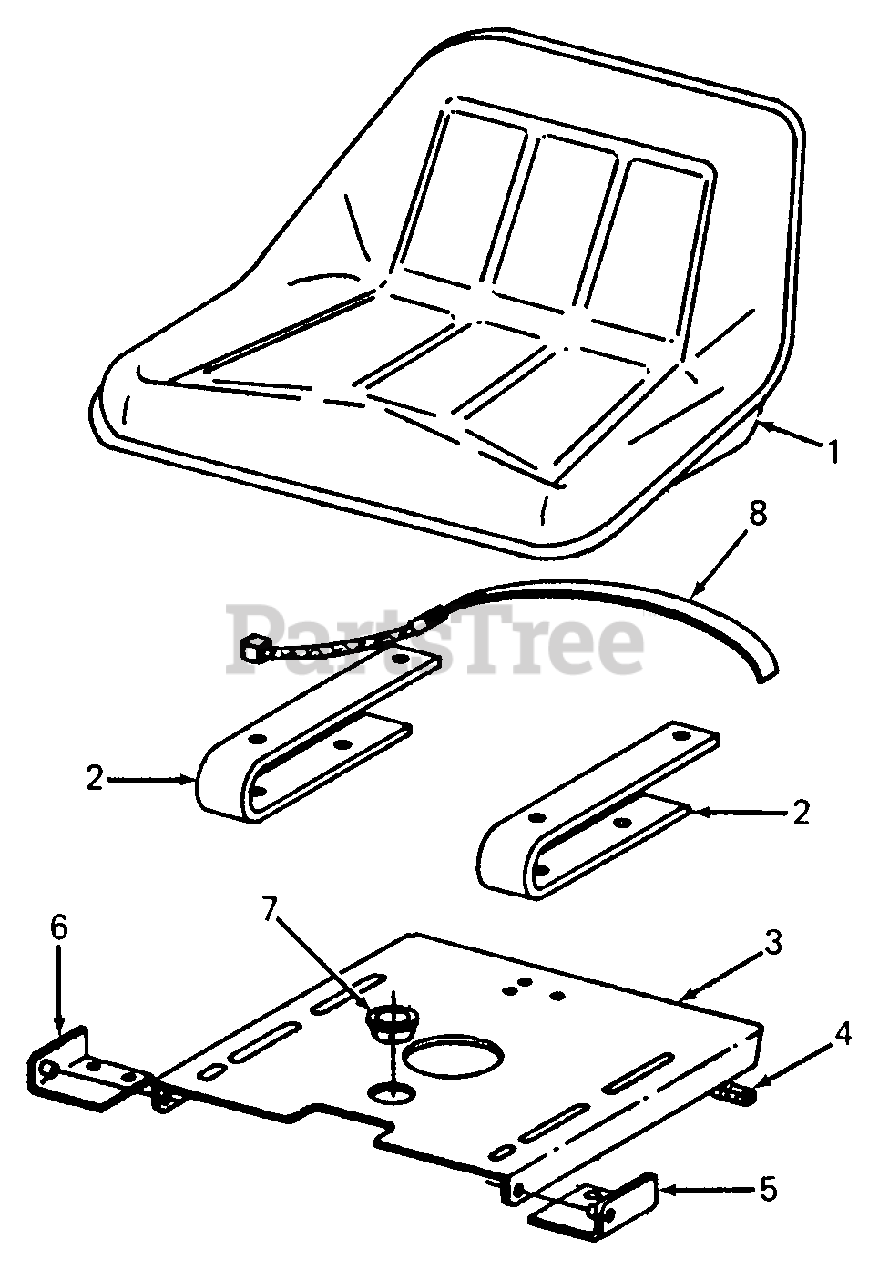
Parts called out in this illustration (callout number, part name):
1	Seat w/Graphic
2	Spring, Seat
7	Bushing, Snap (1.0 ID)
8	Switch Assy, Beam
